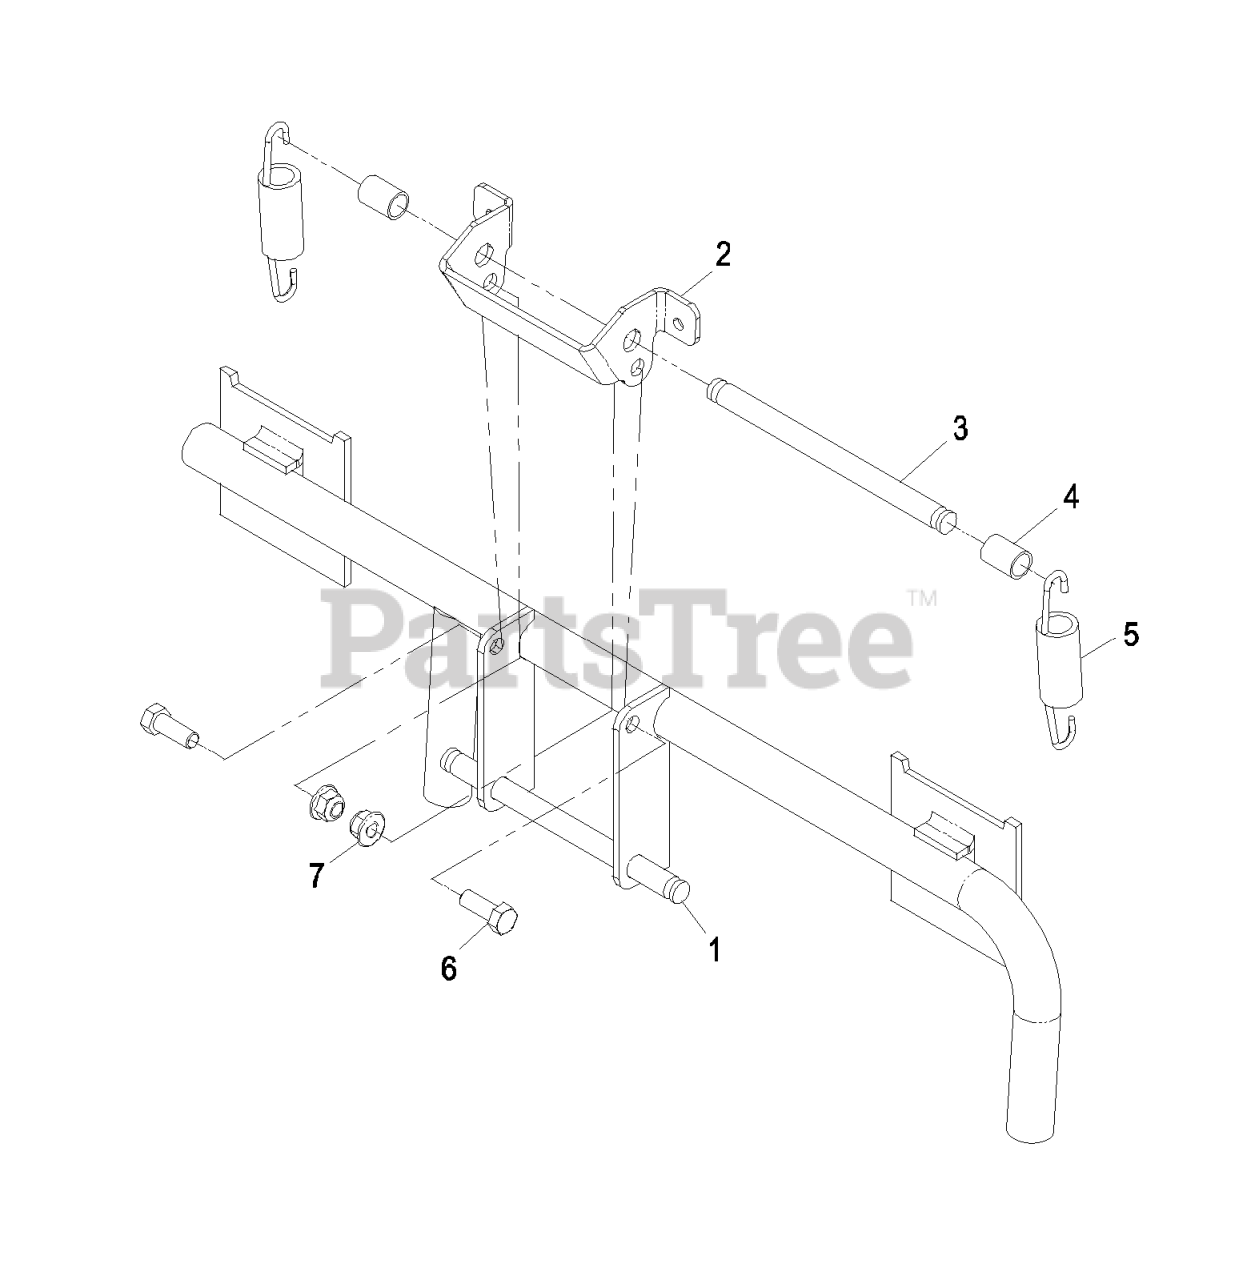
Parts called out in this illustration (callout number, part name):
1	FRAME ASM
2	HINGE-BAGGER TOP
3	PIN-SPRING
5	SPRING-EXTENSION
6	SCREW-HH
7	NUT-HF, NI
